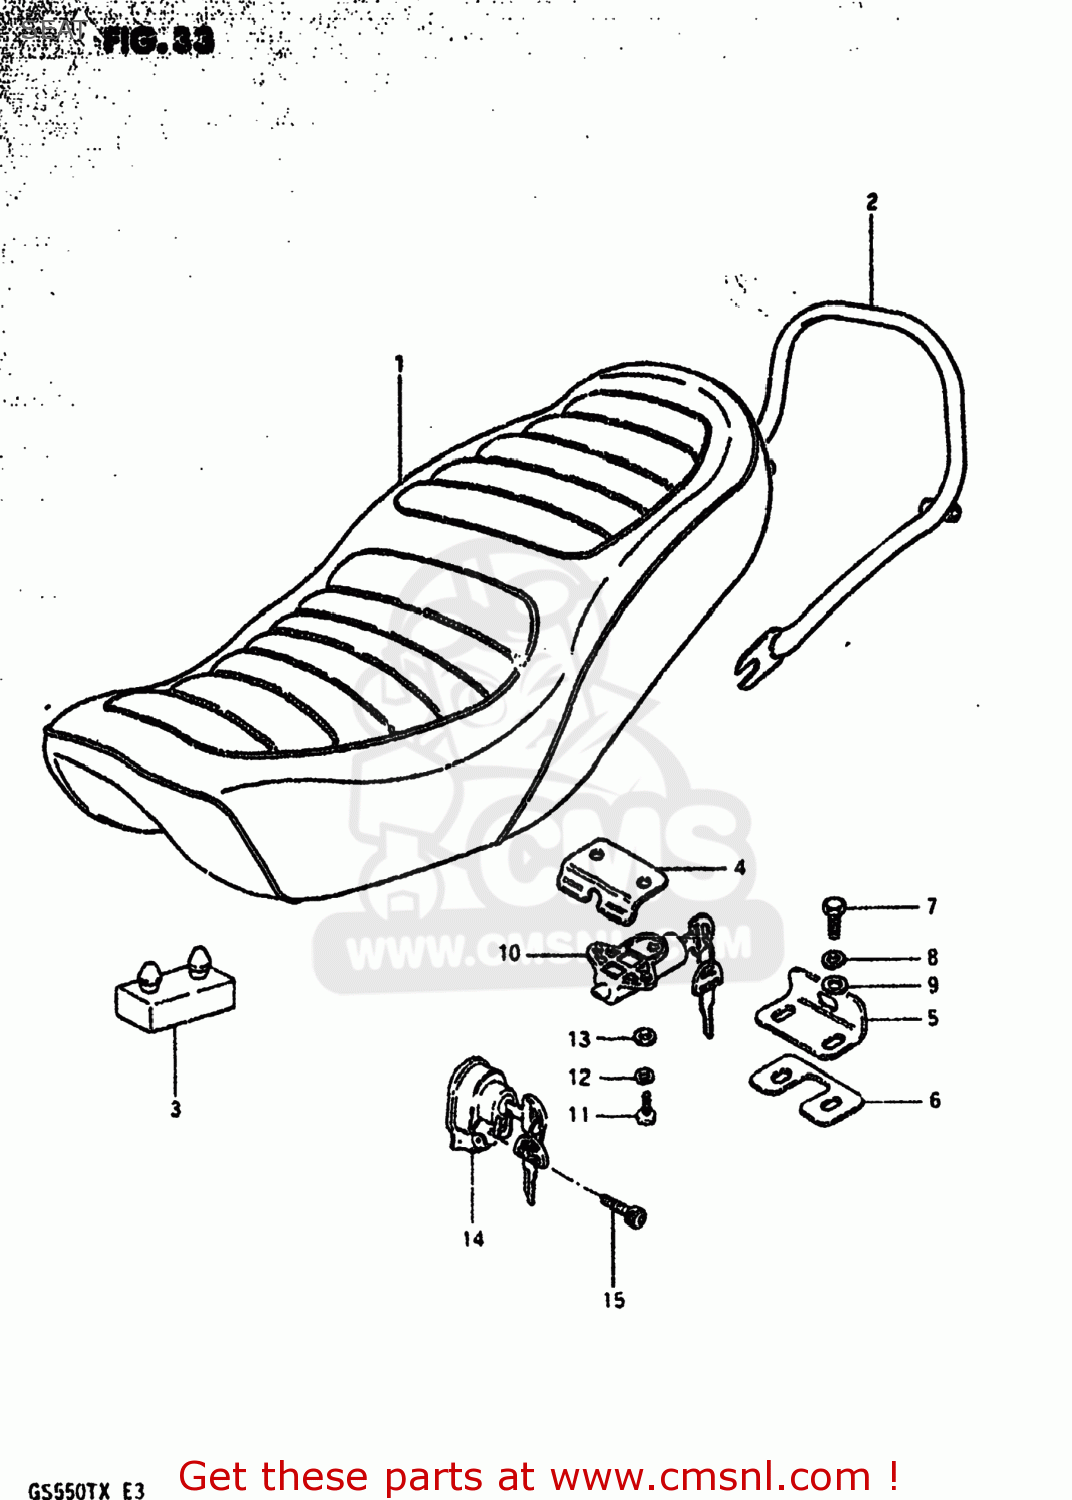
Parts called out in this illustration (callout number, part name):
1	SEAT ASSEMBLY
2	HANDLE,PILLION RIDER
3	CUSHION
4	GUIDE, PLATE
5	STRIKER, SEAT LOCK
6	SHIM,SEAT LOCK STRIKER
7	BOLT
8	LOCK WASHER
9	WASHER
10	LOCK ASSEMBLY,SEAT
11	BOLT
12	LOCK WASHER
13	WASHER
14	LOCK ASSY,HELMET
15	BOLT 5X25
16	CARRIER
17	FITTING SET,CARRIER
